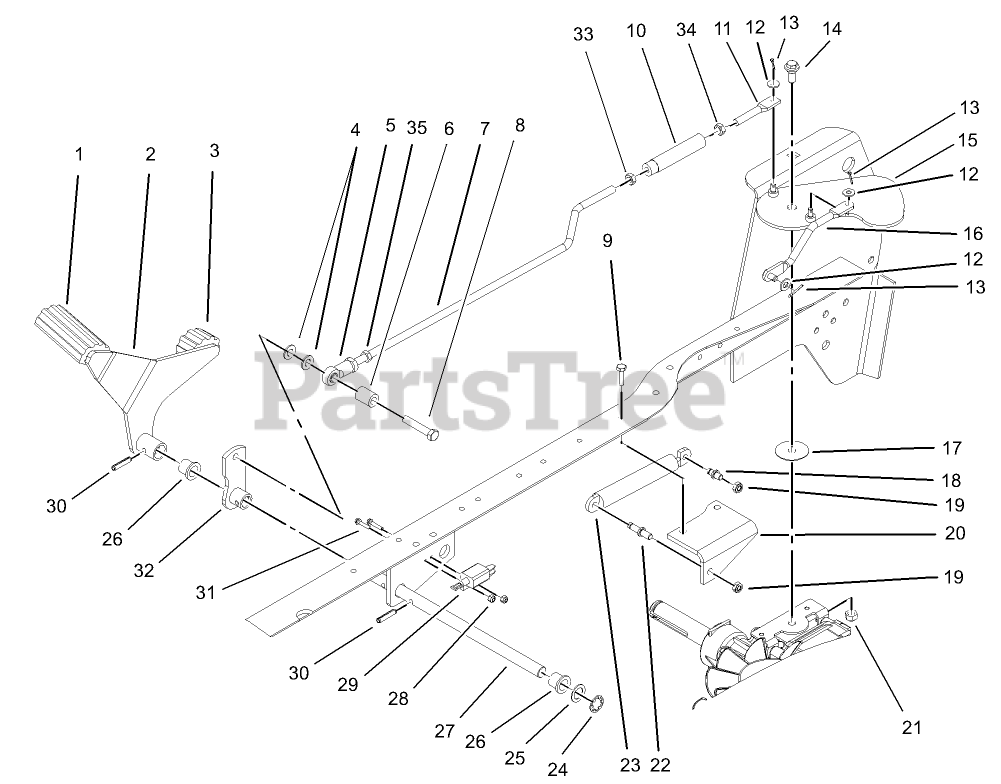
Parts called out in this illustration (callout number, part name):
2	HYDRO PEDAL ASM
3	PAD-PEDAL
4	WASHER-FLAT
5	END-ROD, FEMALE
6	TUBE-INTERLOCK
7	ROD-HYDRO
8	SCREW-HH
9	SCREW-HWHTF
10	TURNBUCKLE
11	LINK-HYDRO
12	WASHER-PLAIN
13	PIN-COTTER
14	BOLT-SHOULDER
15	CRUISE PLATE ASM
16	BELL CRANK ROD ASM
17	SPACER-CRUISE
18	ARM-CONTROL, PIN DAMPER
19	NUT-LOCK, NI
20	BRACKET-DAMPER
21	NUT-HEX
22	PIN-BRACKET, DAMPER
23	DAMPER-GAS
24	RING-RETAINING
25	WASHER-FLAT
26	BUSHING-FLANGE
27	SHAFT-PIVOT, HYDRO
28	NUT-LOCK
29	SWITCH-ADJUSTABLE
30	PIN-SPRING
31	SCREW-SHWH
32	HYDRO LINK ASM
33	NUT-HJ
34	NUT-JAM
35	NUT-JAM
